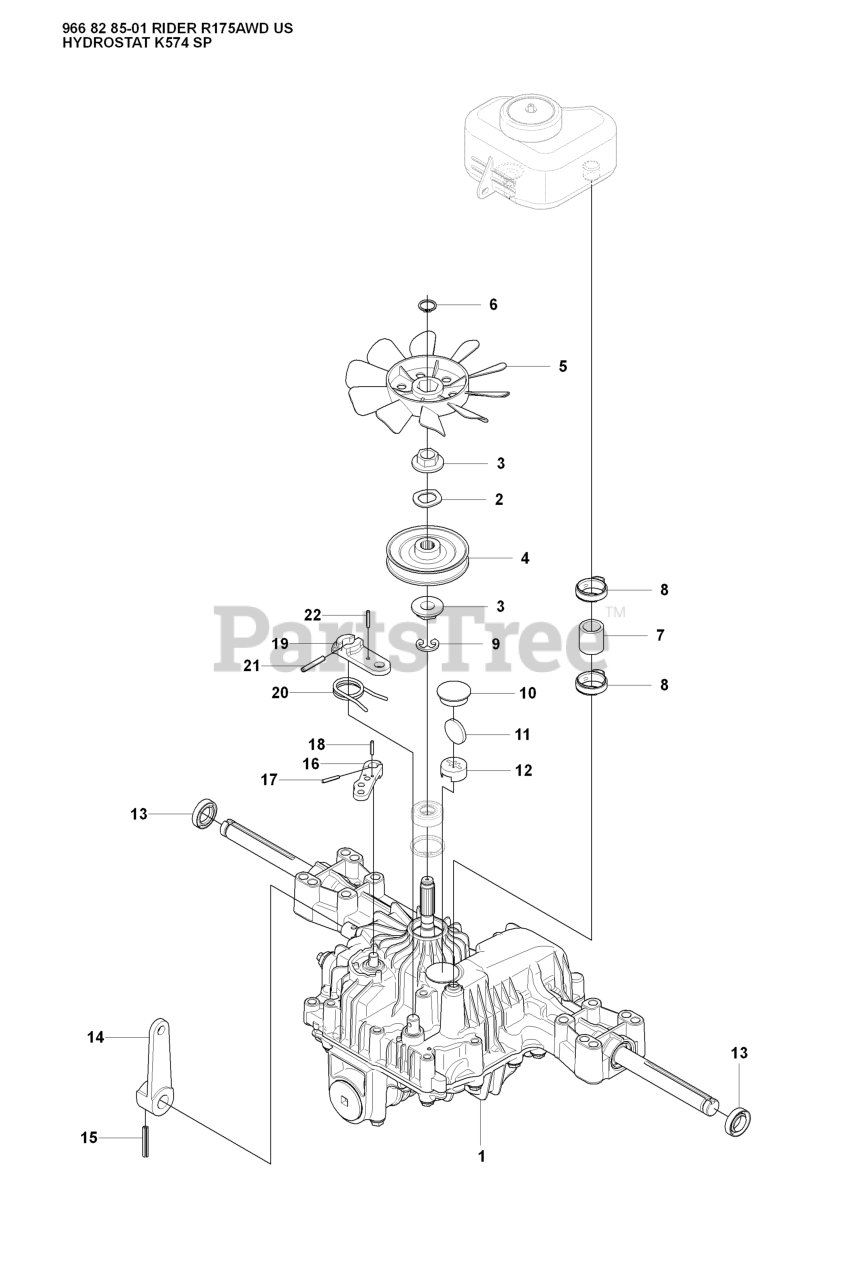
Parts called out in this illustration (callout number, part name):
1	HYDRAULMOTOR
5	FAN.BLACK.1A646083070
6	RETAINING RING **
8	CLAMP
12	MAGNET HOLDER
13	RP SEAL.19, 19216334280
14	CONTROL LEVER
20	RETURN SPRING
